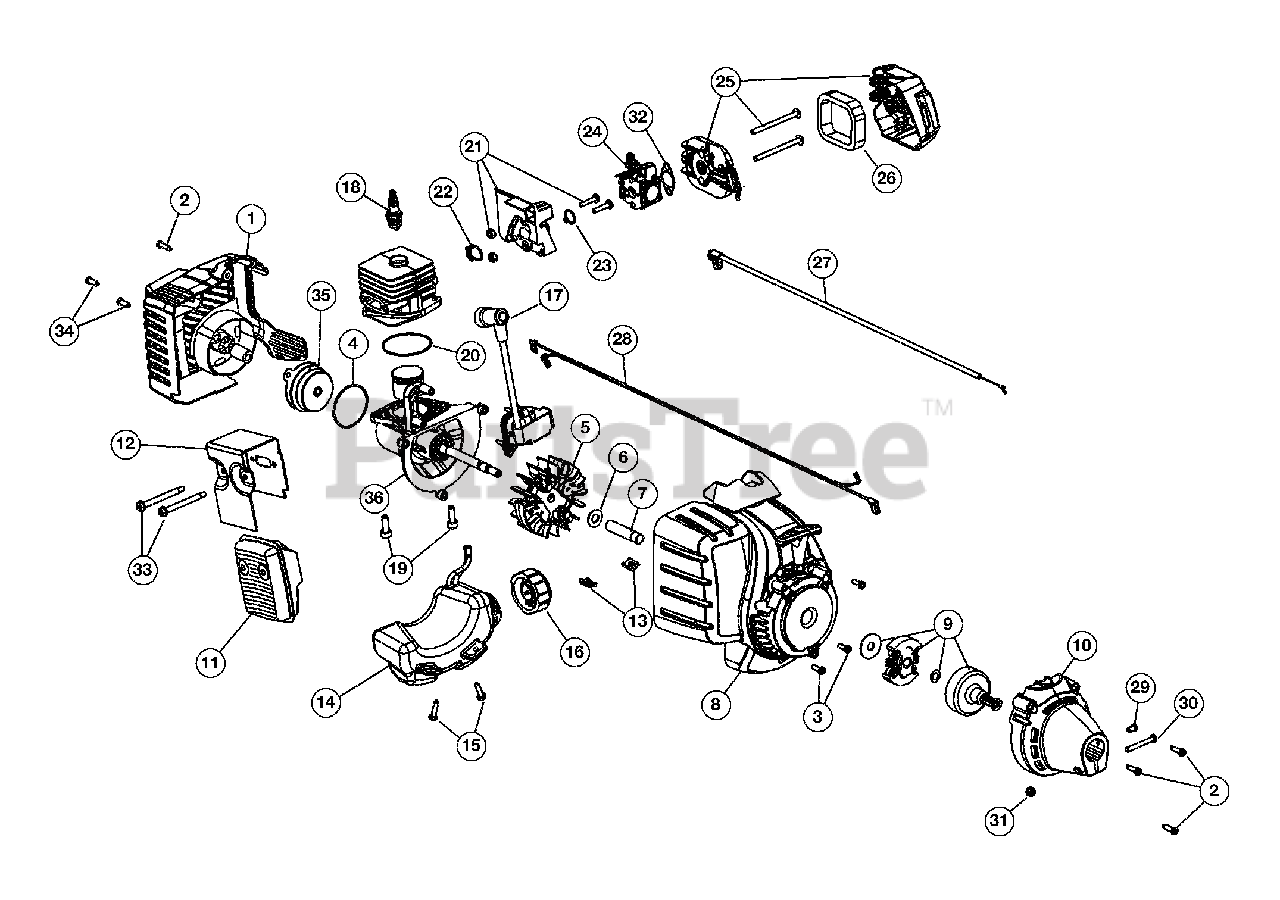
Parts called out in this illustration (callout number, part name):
1	Rear Cover Assembly (Incl. 2 & 34)
2	Cover Screw
3	Housing Screw
5	Flywheel Assembly
8	Starter Housing (Incl. 3 & 13)
9	Clutch Assembly
10	Clutch Cover (Incl. 2)
11	Muffler Assembly (Incl. 12 & 33)
12	Muffler Gasket
13	U-shaped Nut
14	Fuel Tank Assembly (Incl. 15 & 16)
17	Module Assembly
18	Spark Plug
19	Crankcase Bolt
20	Crankcase O-Ring
21	Insulator Assembly (Incl. 22 & 23)
22	Insulator O-Ring
23	Carburetor O-Ring
24	Carburetor
25	Aircleaner Cover Assembly (Incl. 26)
26	Aircleaner Filter
27	Throttle Cable
28	Lead Wires
29	Anti-rotation Screw
30	Clamp Screw
31	Clamp Nut
32	Air Cleaner Gasket
33	Muffler Screw
34	Rear Housing Screw
35	Electric Starter Cover Assembly
36	Short Block Assembly (Incl. 4-7 & 17-20)
